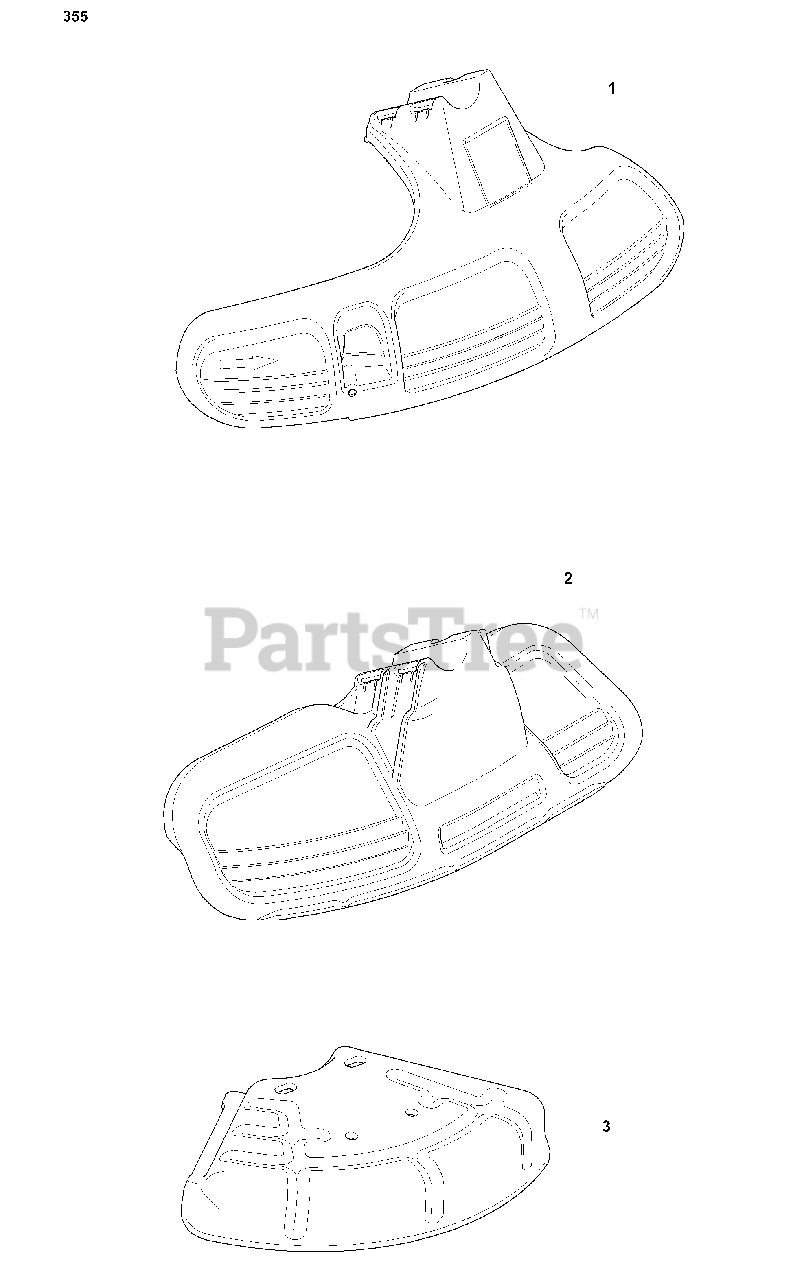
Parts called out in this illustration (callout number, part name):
1	PROTECTION
2	BLADE GUARD GRASS
3	BLADE GUARD SAW
